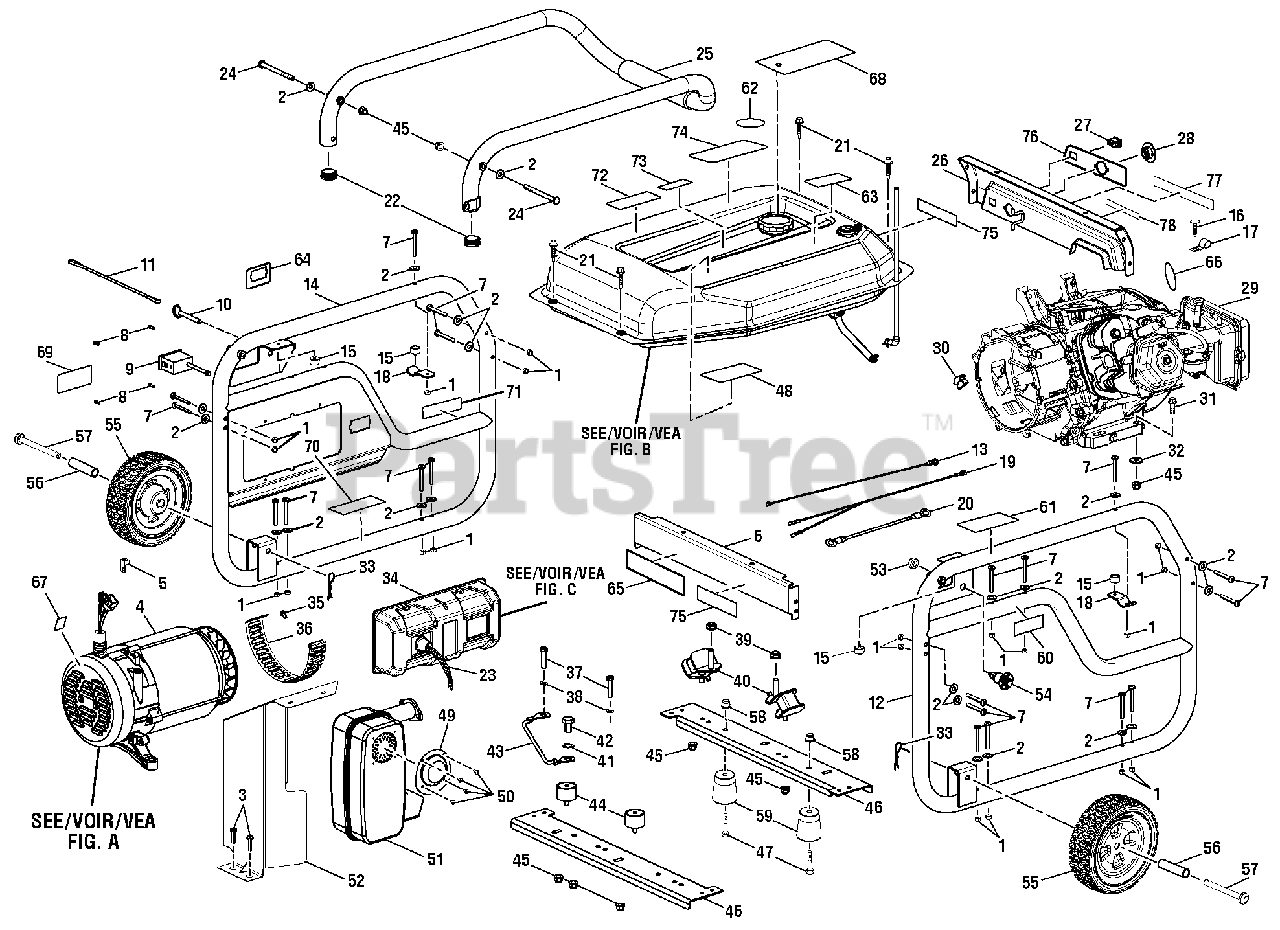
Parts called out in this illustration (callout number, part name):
1	Lock Nut (M6)
2	Washer (1/4 in.)
3	Bolt (3/8 in. x 3/4 in.)
4	Generator Head Assembly (See Figure A)
5	Ground Lug (1/4-20)
6	Fuel Tank Support (Rear)
7	Screw (M6 x 50 mm, Pan Hd.)
8	Screw (6-20 x 3/8 in.)
9	Analog Hour Meter
10	Pin Release
12	Frame (Left)
13	Wire Assembly (Green)
14	Frame (Right)
15	Rubber Bumper
18	Handle Bracket
19	Assembly Wire (Black)
20	Bonding Wire
21	Screw (1/4-14 x 1.25 in.)
22	End Cap (Handle)
23	Wire Sleeving
24	Screw (M8 x 98 mm, Flat Hd.)
25	Handle Assembly
26	Fuel Tank Support (Front)
27	On/Off Switch
28	Fuel Valve Bezel
29	Engine (LCT)
30	Rubber Plug
31	Bolt (M8 x 40 mm, Hex Hd.)
32	Washer (5/16)
33	Hitch Pin
34	Control Panel Assembly (See Fig. C)
35	Bolt (M5 x 10 mm, Hex Hd.)
36	Fan Cover
37	Bolt (M8 x 1.25 in., Hex Hd.)
38	Lock Washer (M8)
39	Lock Nut (M10)
40	Isolator (Large)
41	Star Washer (M8)
42	Bolt (M6 x 16 mm, Flange Hd.)
43	Ground Wire Assembly
44	Isolator (Small)
45	Flange Nut (M8)
46	Reversible Cross Plate
47	Bolt (M8 x 45 mm, Hex Hd.)
48	Combustion Label
49	Spark Arrestor Screen
50	Screw (8-32 x 3/8 in., Pan Hd.)
52	Heat Shield
53	Hex Nut (1/2-20)
54	Handle Lock Assembly
57	Axle Bolt
58	Lock Nut (M8 x 1.25)
59	Rubber Foot
60	Hot Surface Label
61	Handle Release Label
62	Fuel Stabilizer Label
63	Danger Label
64	Systems Monitor Label
65	Ground Warning Label
66	Recoil Housing Label
67	Ground Label
68	Warning Hang Tag
69	Lock and Pin Label
70	Lubricant Label
71	Inquires label
72	Fire Danger Label
73	E85 Label
74	CPSC Label
75	Fire Distance Label
76	Fuel Label
77	Logo Label
78	Start Label
